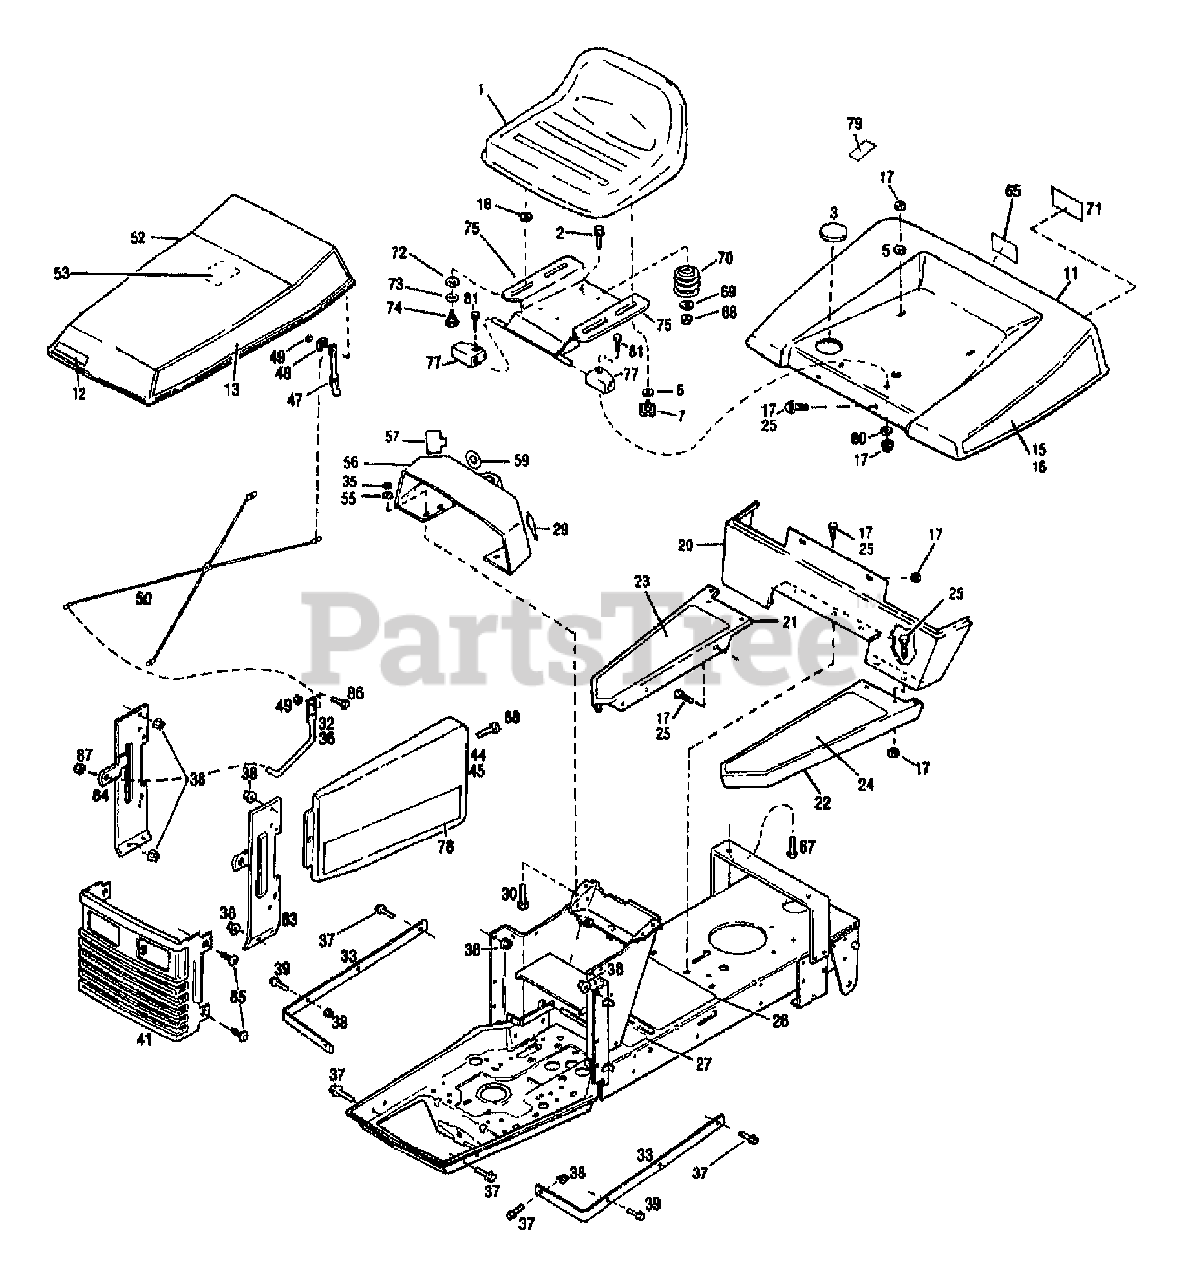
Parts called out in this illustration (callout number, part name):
2	SCR-HFLK 3/8-16X1.00 ZP
5	WASHER-1.25X.343X.059
11	FENDER-REAR
12	DECAL-LOGO
13	DECAL-LOGO
15	DECAL-FENDER RH RED
16	DECAL-FENDER LH RED
17	NUT-HFLK 5/16-18 ZP
18	WASHER-FLAT
20	SUPT-RUNNING BOARD
21	BOARD-RUNNING RH
22	BOARD-RUNNING LH
23	PAD-FOOT RH
24	PAD-FOOT LH
25	SCR-LOCK
26	PAD-FOOT
27	DECAL-OPERATING INST
29	DECAL-CHOKE
30	SCR-HH 1/4-20X.625 G5 ZP
32	LINK-HINGE RH
33	ASSM-HINGE STRAP
35	NUT-HT/LK 1/4-20
36	LINK-HINGE LH
37	SCR-HH 1/4-20X.625
38	NUT-HF/LK 1/4-20 ZP
39	SCR-HFLK 1/4-20X.50 ZP
44	COVER-SIDE LH
45	COVER-SIDE RH
47	LATCH-RUBBER
49	NUT W/LKWASHER 10-24 ZP
50	SUPPORT-HOOD ROD
52	ASSM-HOOD
53	DECAL-SVC INST
55	WASHER-FLAT 1/4 SAE
56	PANEL-INSTRUCTION
57	DECAL-THROTTLE
59	DECAL-IGNITION
65	DECAL-FUEL
67	SCR-CARR 5/16-18X.75
68	NUT-HFLK 3/8-16 ZP
69	WASHER-FLAT 1.25X.406X.179
70	SPRING-COMPRESSION
71	DECAL-LOGO FENDER
72	WASHER-BOW .74X.52X.01
73	WASHER-1.06X.51X.09 NYLON
74	SCR-SHLDR 3/8-16X.25 G5ZP
75	ASSM-SEAT SUPPORT
77	BLOCK-PIVOT
78	DECAL-SIDECVR LH RED
78	DECAL-SIDECVR RH RED
79	DECAL-U.S.A.
81	SCR-HH 5/16-18X1.5 G5 ZP
83	ASSM-SUPPORT LH
84	ASSM-SUPPORT RH
86	SCR-HHS 10-24X.625 ZP
87	NUT-SPECIAL
